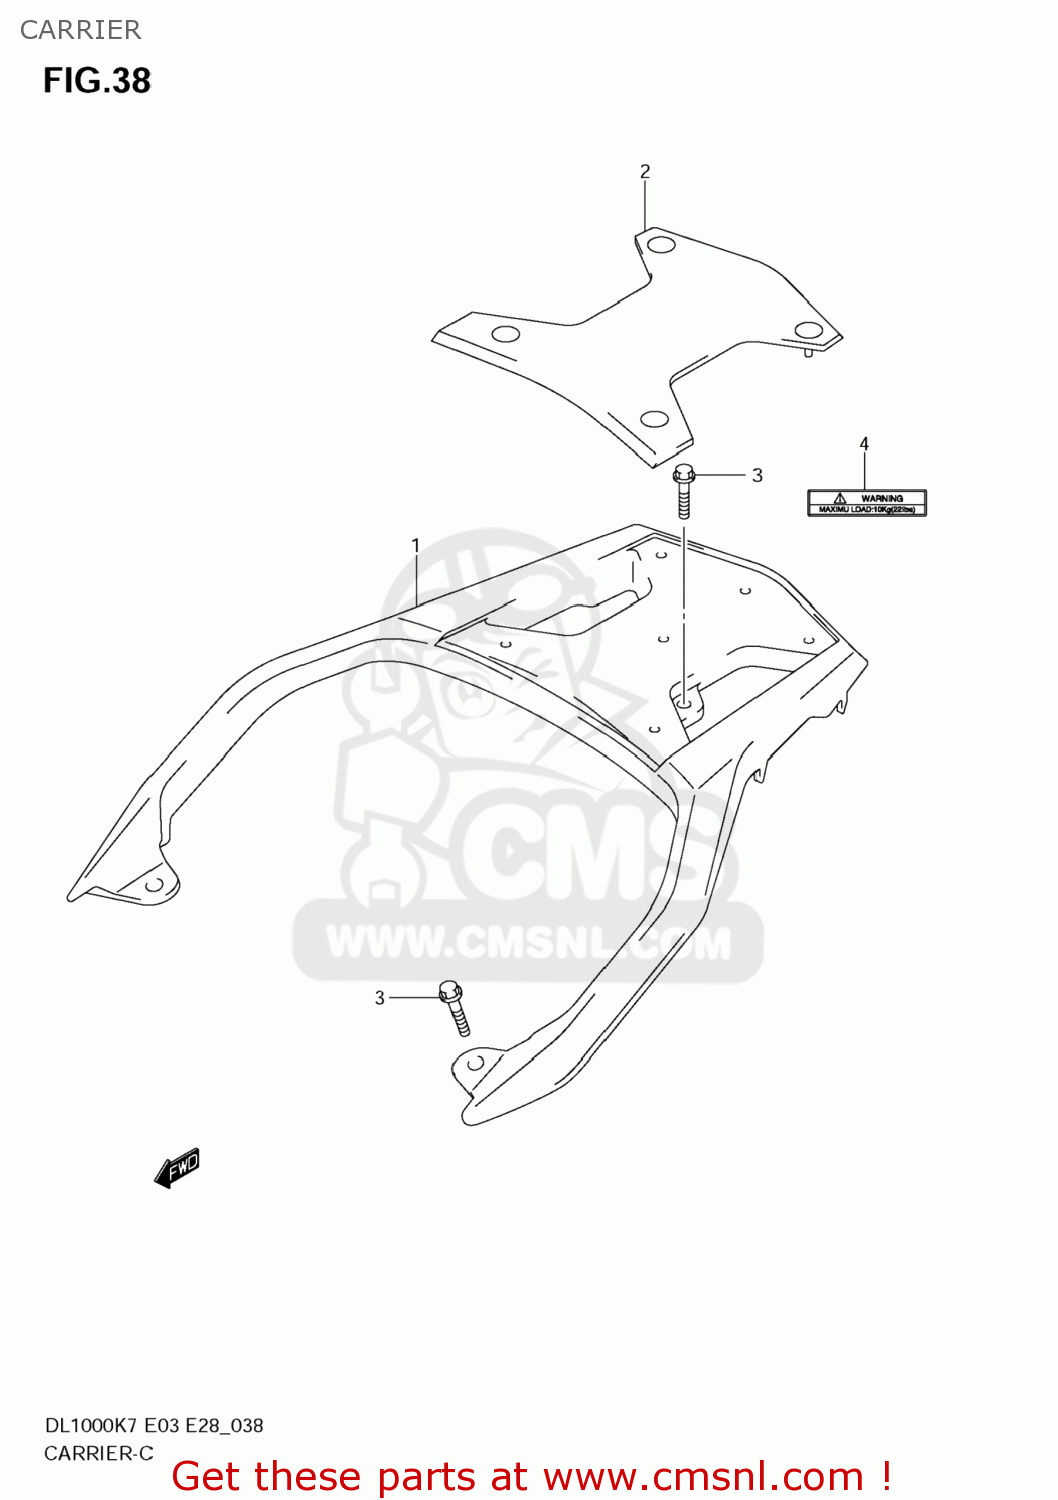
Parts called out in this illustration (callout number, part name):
1	CARRIER,SPORT
2	MAT,SPORT CARRIER
3	BOLT(8X35)
4	LABEL,CARRIER
